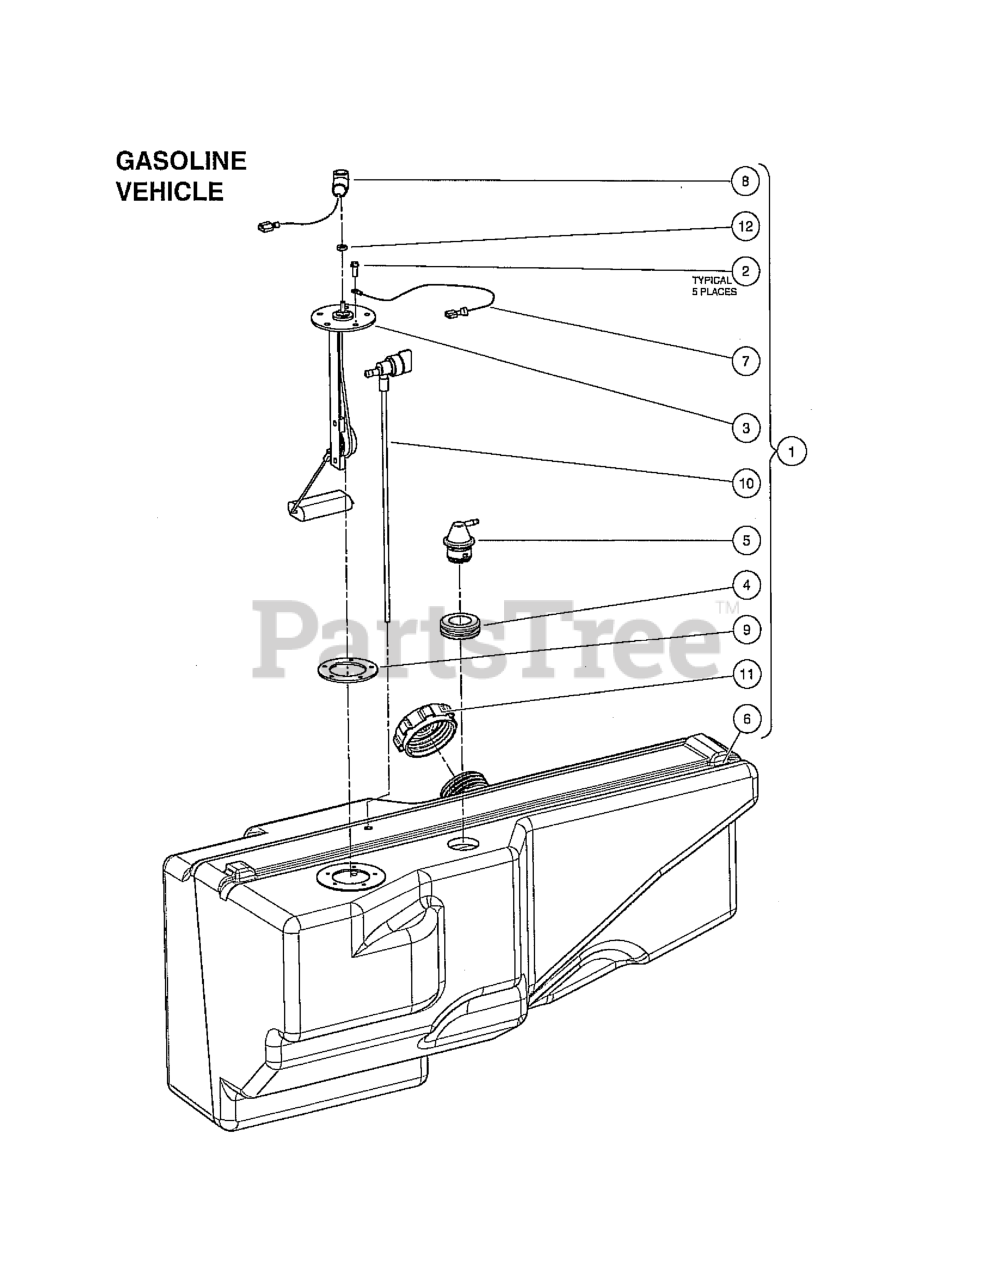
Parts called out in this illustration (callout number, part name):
1	ASM, TANK, GASOLINE, SIDEFILL
4	INSULATION GROMMET
5	FUEL TANK VENT ASSY
9	GASKET, SEND UNIT (RUBBER)
11	CAP
12	NUT, #10-32 BRASS HEX
